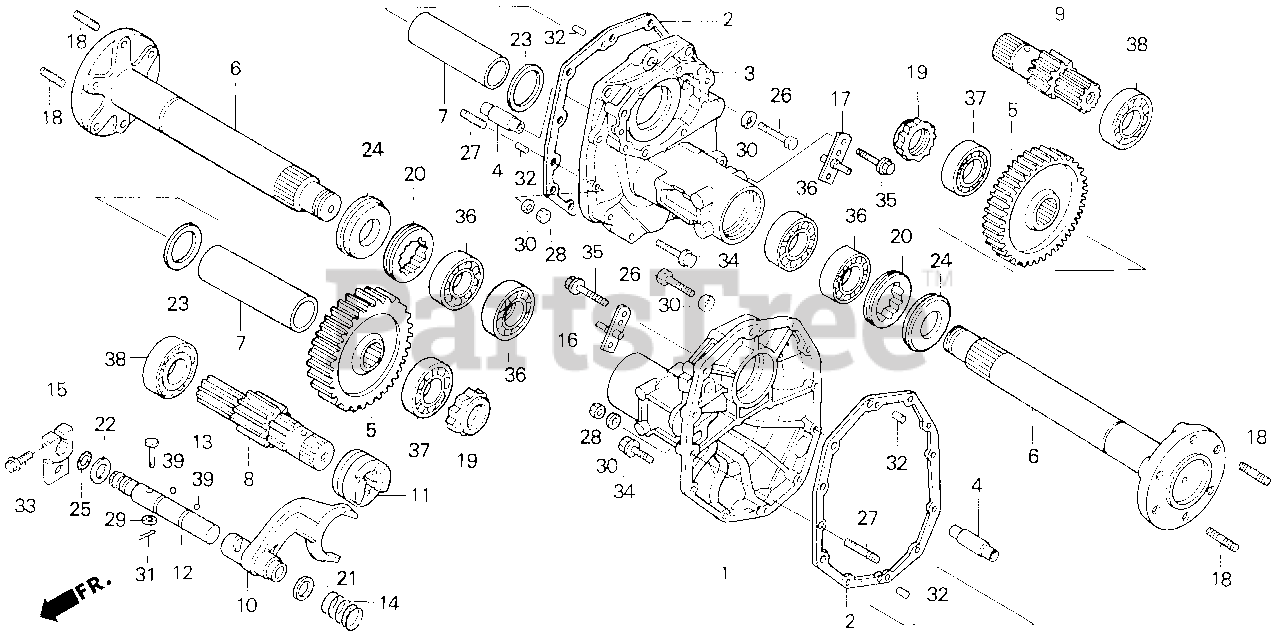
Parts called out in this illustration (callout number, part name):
1	HOUSING, R. RR. AXLE
2	GASKET, RR. AXLE HOUSING
3	HOUSING, L. RR. AXLE
4	PIPE, OIL GALLERY
5	GEAR, RR. FINAL DRIVEN
6	SHAFT, RR. AXLE
7	COLLAR, RR. AXLE
8	SHAFT, R. RR. DRIVE
9	SHAFT, L. RR. DRIVE
10	FORK, DIFFERENTIAL LOCK
11	SHIFTER, DIFFERENTIAL LOCK
12	SHAFT, DIFFERENTIAL LOCK
13	PIN, DIFFERENTIAL LOCK
14	SPRING, DIFFERENTIAL LOCK RETURN
15	ARM, DIFFERENTIAL LOCK
16	SHAFT, LINK (LOWER)
17	SHAFT, L. LINK (LOWER)
18	BOLT, STUD (16X25)
19	NUT, LOCK (35MM)
20	NUT, LOCK (78MM)
21	WASHER, THRUST (24MM)
22	WASHER (16MM)
23	WASHER, THRUST (45.2X60X2)
24	SEAL, WATER (45X81X13.8)
25	O-RING (13.5X1.5) (ARAI)
26	BOLT, HEX. (10X40)
27	BOLT, STUD (10X32)
28	NUT, HEX. (10MM) (NOT AVAILABLE)
29	WASHER, PLAIN (6MM)
30	WASHER, SPRING (10MM)
31	PIN, COTTER (2.0X15)
32	PIN, DOWEL (8X14)
33	BOLT, FLANGE (6X20)
34	BOLT, FLANGE (12X60)
35	BOLT, FLANGE (12X65)
36	BEARING, RADIAL BALL (6009)
37	BEARING, RADIAL BALL (6307)
38	BEARING, RADIAL BALL (6307)
39	BALL, STEEL (#4)
